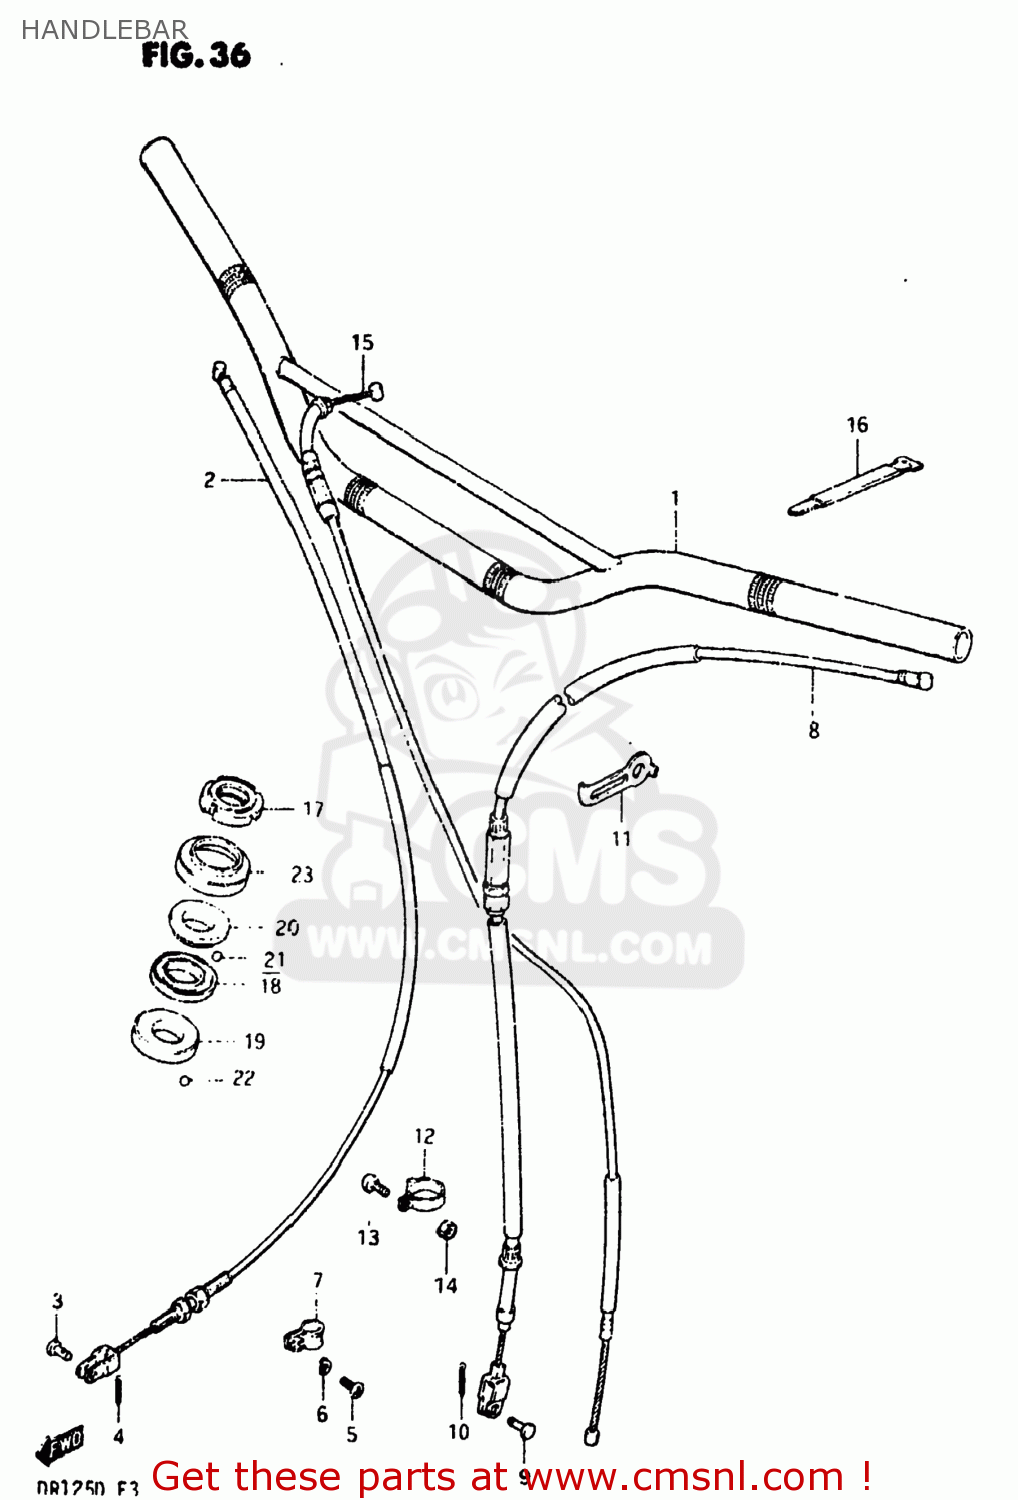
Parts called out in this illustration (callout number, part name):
1	HANDLEBAR
2	CABLE,FRONT BRAKE
3	PIN(L:17.5)
4	PIN
5	SCREW 6X12
6	LOCK WASHER
7	CLAMP,FR BRAKE CABLE
8	CABLE ASSEMBLY,CLUTCH
9	PIN(L:15)
10	PIN
11	CLAMP,CABLE
12	CLAMP,CABLE
13	SCREW
14	NUT
15	CABLE ASSY,THROTTLE
16	CLAMP
17	NUT,STEERING STEM(25X44X10)
18	RACE,STEERING INNER UPR
19	LACE,STEERING INNER LWR
20	RACE,STEERING OUTER UPR
21	BALL
22	BALL
23	DUST SEAL,STEERING UPR
